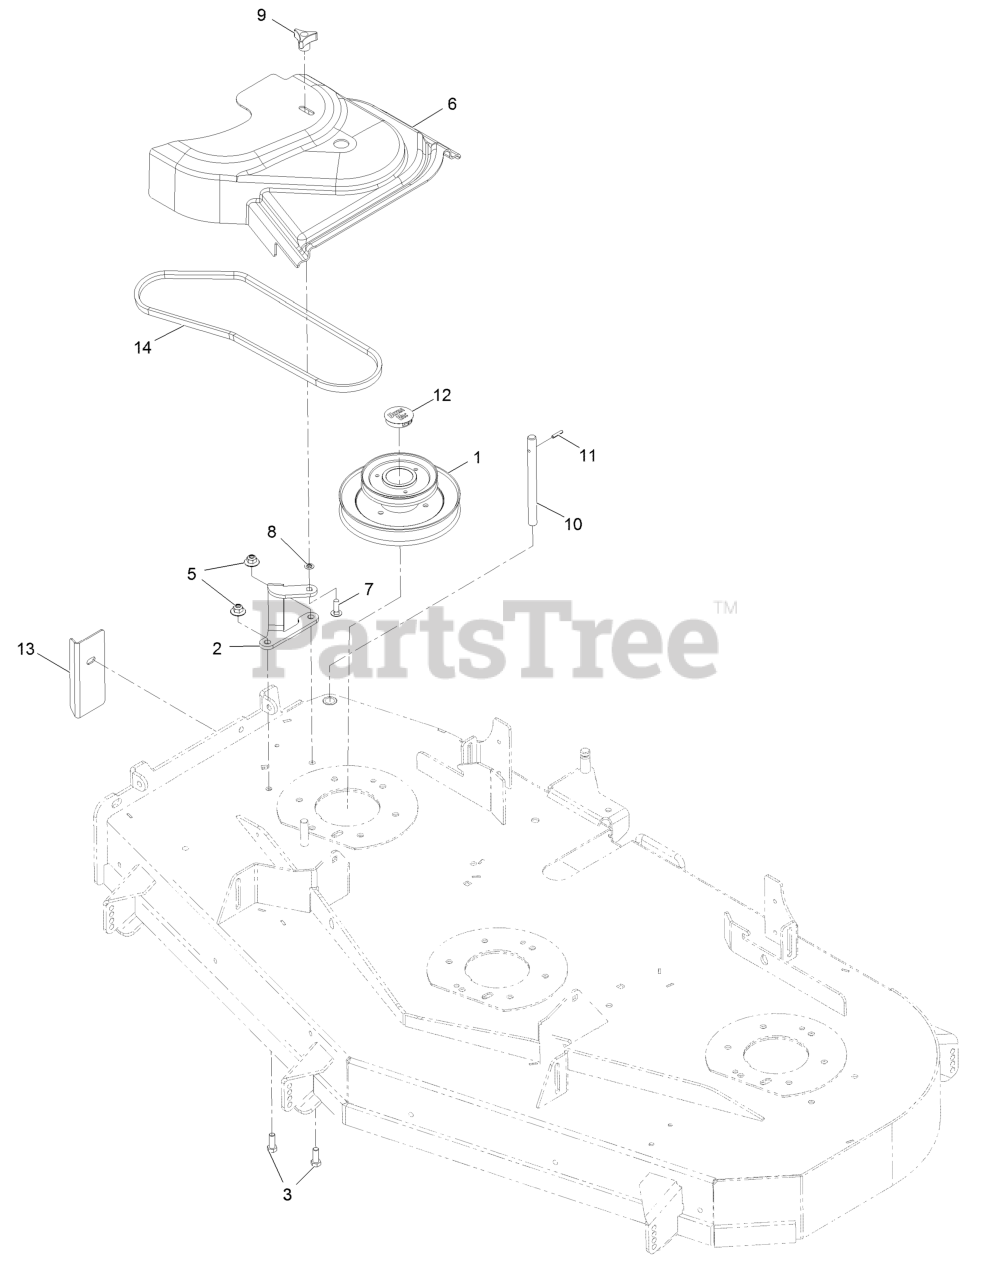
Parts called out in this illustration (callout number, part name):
1	JACKSHFT- UV DRIVE 603
2	BRACKET,BELT COVER
3	SCREW-HH
5	Nut-Nyloc 3/8-16 Flg
6	COVER-BELT UVE 60
7	BOLT-CARR
8	RING-RETAINING, BOLT
9	KNOB-3 PRONG
10	SHAFT-CATCHER, GRASS
11	PIN-ROLL
12	PLUG, BLACK NYLON 1.75
13	PLATE-BLOCKER
14	BELT- 4L SECTION
